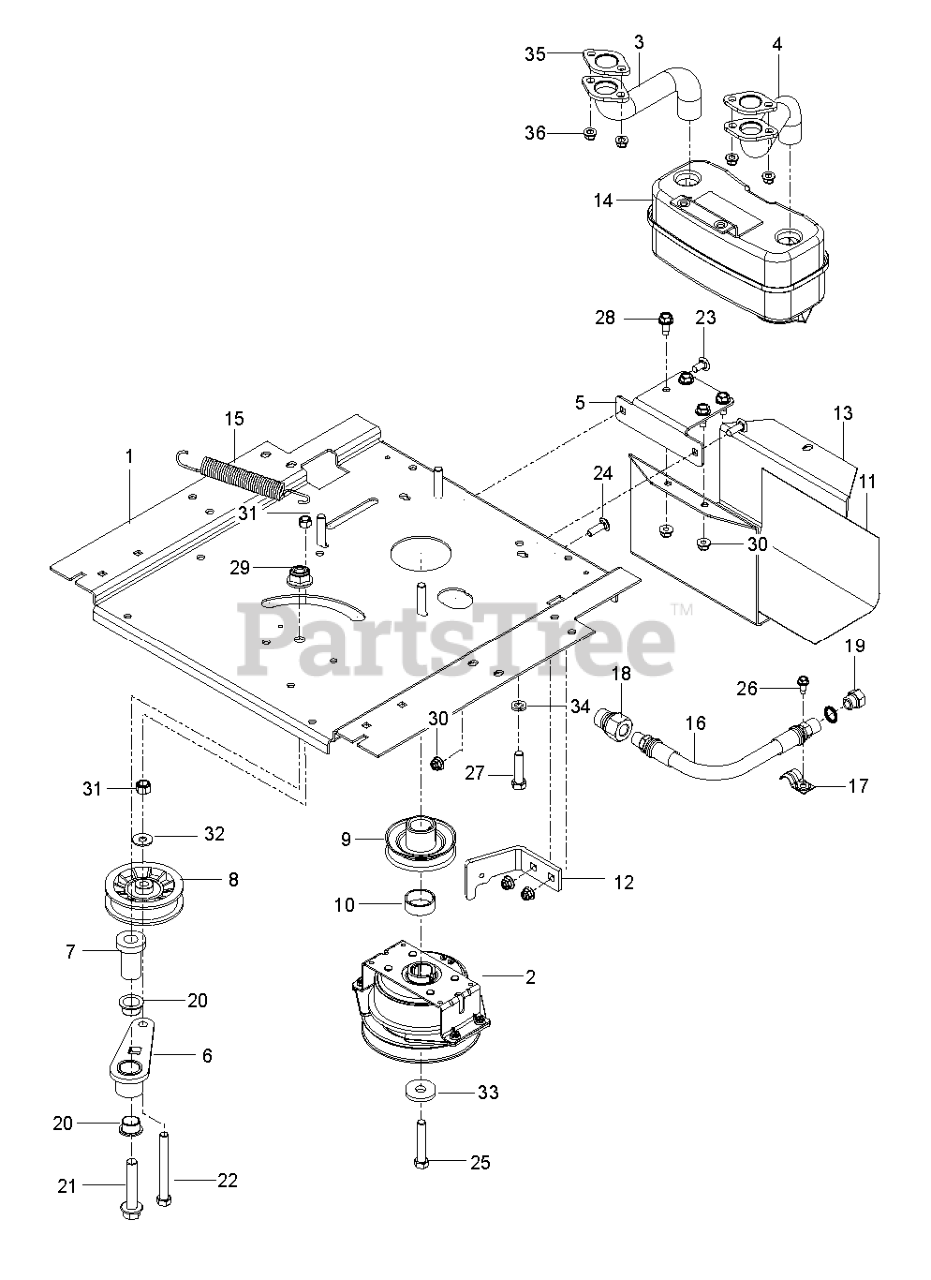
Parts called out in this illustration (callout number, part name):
1	PLATE ENGINE; RZ, 23IN BLACK
2	CLUTCH.OGURA.5.0PD.GT1.5A-EH07
3	TUBE.EXHAUST.RH.FR961/FR730
4	TUBE.EXHAUST.LH.FR961/FR730
5	BRACKET MUFFLER MS431BLK
6	ARM IDLER
7	SPINDLE.IDLER
8	PULLEY, IDLER RAKE & ZTR
9	PULLEY.ENGINE
10	SPACER.SPACER.625 W/OGURA.LCC
11	HEAT SHIELD
12	CLUTCH.STOP.OGURA LCC.BLACK
13	GUARD.MUFFLER.WO.TOW.HITCHX431
14	MUFFLER ASM TWIN
15	SPRING, DECK DRIVE
16	HOSE.ASSEMBLY.OIL.DRAIN
18	ADAPTER, OIL DRAIN
19	PLUG OIL DRAIN
20	BEARING.FLANGED.PLASTIC.3/4ID
21	BOLT.FLANGE.1/2-13 X 2.75.GRD5
22	HCS 3/8-16X3-1/2 TAPBLT GR5 ZD
23	RHSNB 5/16C X 1
24	BOLT 5/16C X 3/4" CARRIAGE
25	CLUTCH BOLT7/16-20X2.5 GR524HR
26	SCR 1/4-20X5/8 HEX SELF TAP ZD
27	BOLT
28	SCREW.THDROL.5/16-18X3/4.TTY
29	NUT, 1/2-13 HEX FLG NYLOC ZD
30	5/16-18 NYLOC FLANGE NUT
31	NUT 3/8-16 NYLOC
32	WASHER 5/16 FLAT
34	SLW 3/8 STD
36	NUT.HEX.FLANGE.TOPLOCK
